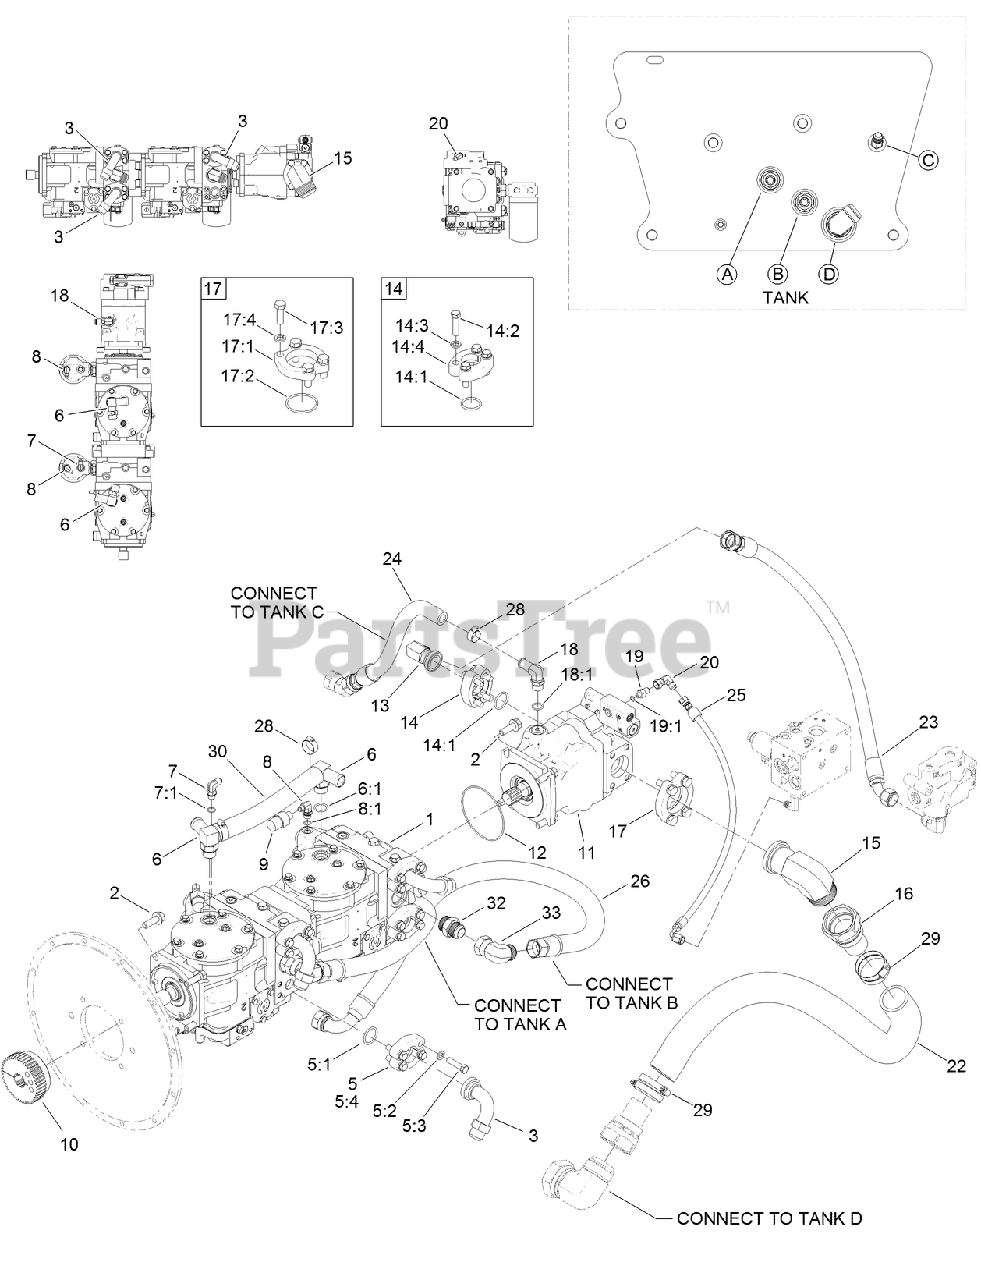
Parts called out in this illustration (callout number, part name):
1	TANDEM PUMP ASM
2	SCREW-HHF
3	FITTING-ELBOW
5	HYD FLANGE KIT
5:1	O-RING
5:2	WASHER-LOCK
5:3	SCREW-HH
6	CONNECTOR
6:1	O-RING
7	FITTING-ELBOW, 90 DEG
7:1	O-RING
8	FITTING-ELBOW, 90
8:1	O-RING
9	SWITCH-PRESSURE
10	HUB-COUPLER
11	HYD PUMP ASM
12	SEAL-O RING
13	ADAPTER-FLANGE, SPLIT
14	FLANGE KIT
14:1	O-RING
14:2	SCREW-HH
14:3	WASHER-LOCK
14:4	CODE 61 SPLIT FLANGE HALF
15	ADAPTER-FLANGE, SPLIT
16	FITTING-STRAIGHT
17	FLANGE KIT
17:2	O-RING
17:3	SCREW-HH
17:4	WASHER-LOCK
18	FITTING-90
18:1	O-RING
19	ADAPTER-STRAIGHT
19:1	O-RING
20	ELBOW-SWIVEL, 90 DEG
22	HOSE-FUEL, TANK FILL
23	HYD HOSE ASM, HP
24	HYD HOSE ASM, LP
25	HYD HOSE ASM
26	HYD RETURN HOSE ASM
28	CLAMP-HOSE
29	CLAMP-HOSE
32	FITTING-STRAIGHT
33	FITTING-ELBOW, 90
